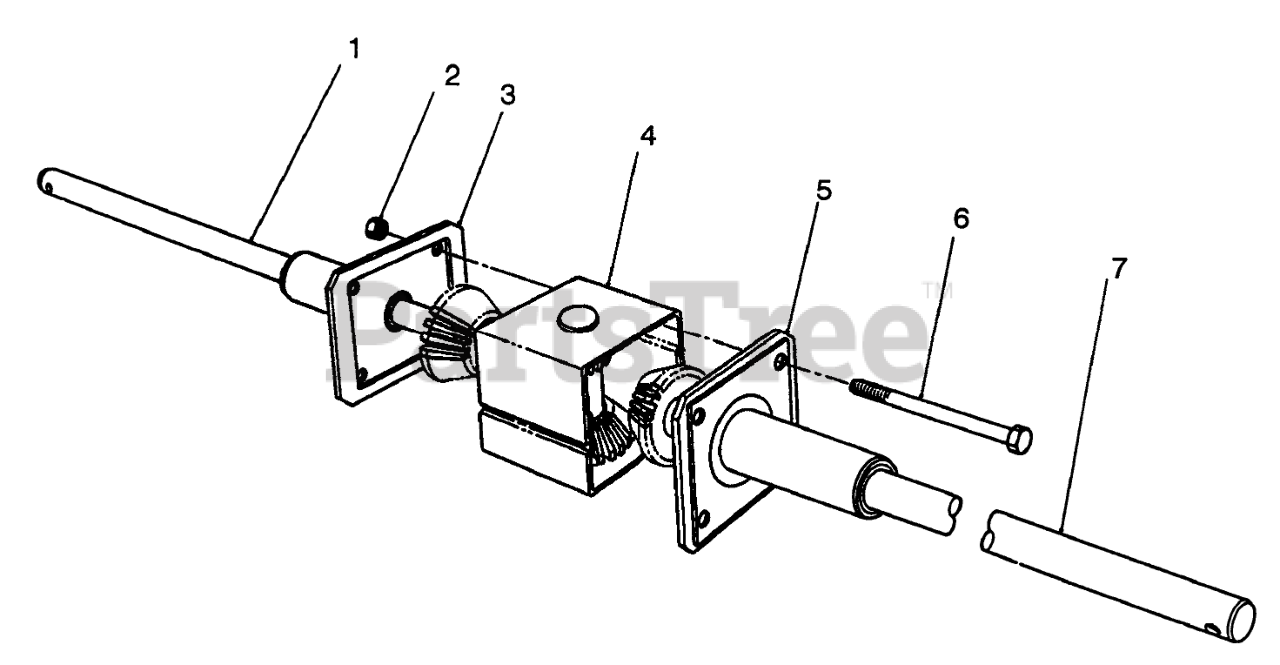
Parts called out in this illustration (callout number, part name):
2	NUT-LOCK, CONE
3	END CAP/BRG ASM
4	GEAR CASE ASM
5	END CAP &BEARING ASY
6	SCREW-HH
